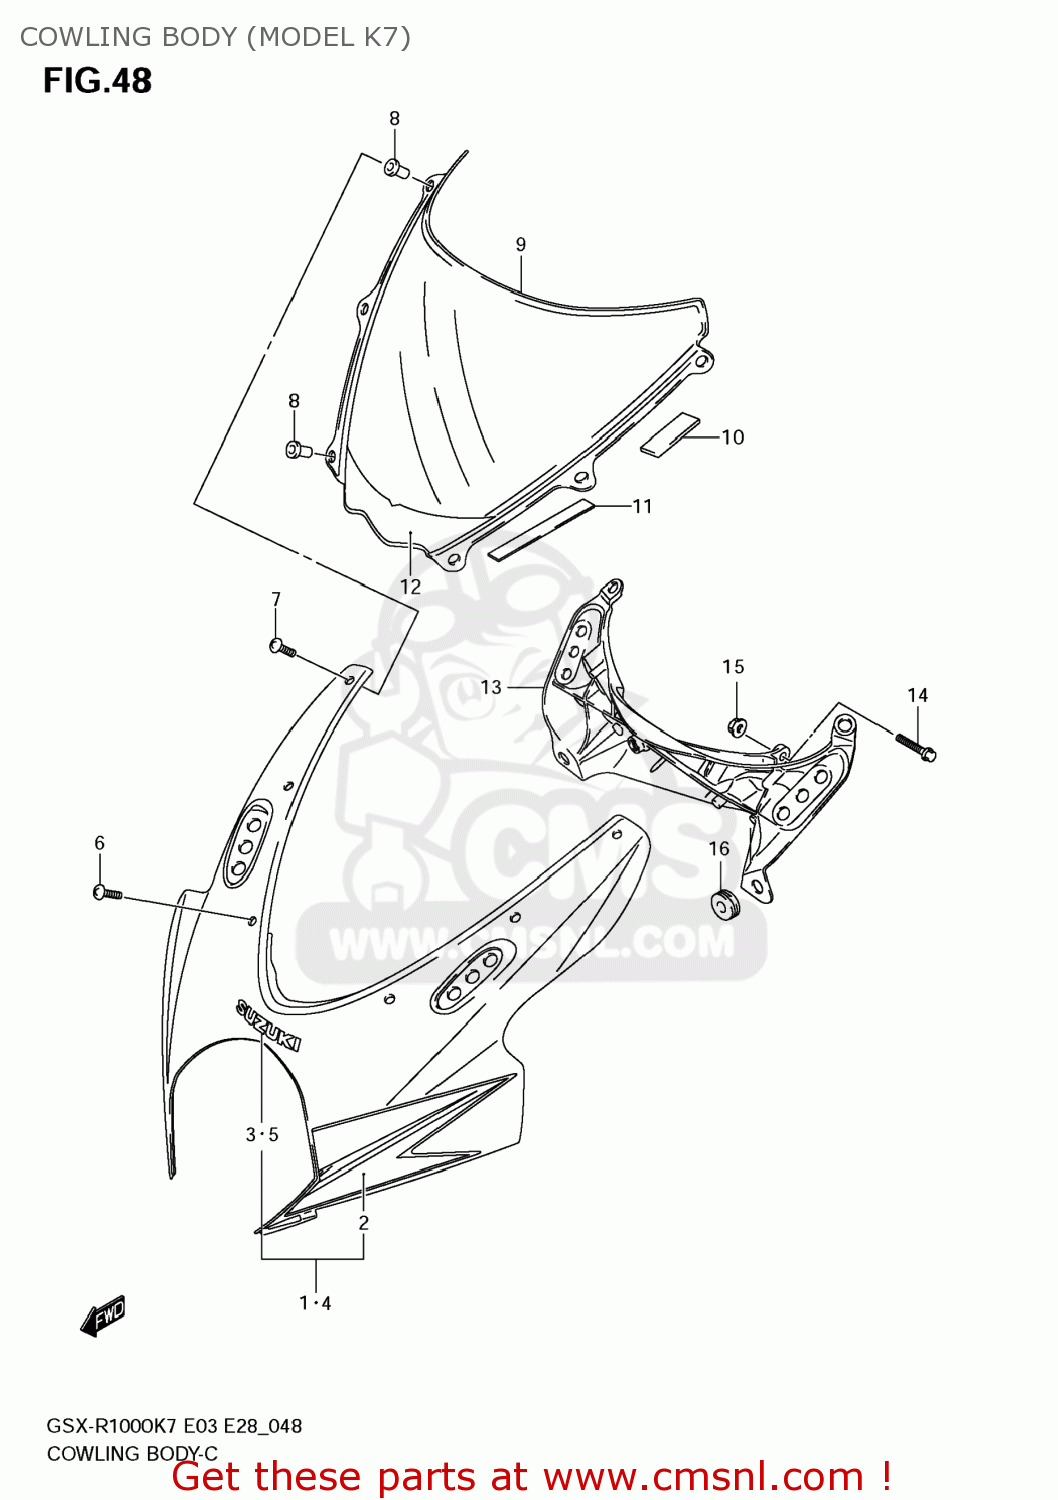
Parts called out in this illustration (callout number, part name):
1	BODY,COWLING(BLUE)
2	TAPE SET,BODY COWL
3	EMBLEM,SUZUKI
4	BODY,COWLING(BLACK)
5	EMBLEM,SUZUKI
6	SCREW(5X18)
7	SCREW(5X15)
8	NUT
9	WINDSCREEN
10	TAPE(6X25X0.13)
11	CUSHION,WINDSCREEN
12	TAPE,SCREEN
13	BRACE,COWLING
14	BOLT
15	NUT
16	CUSHION
